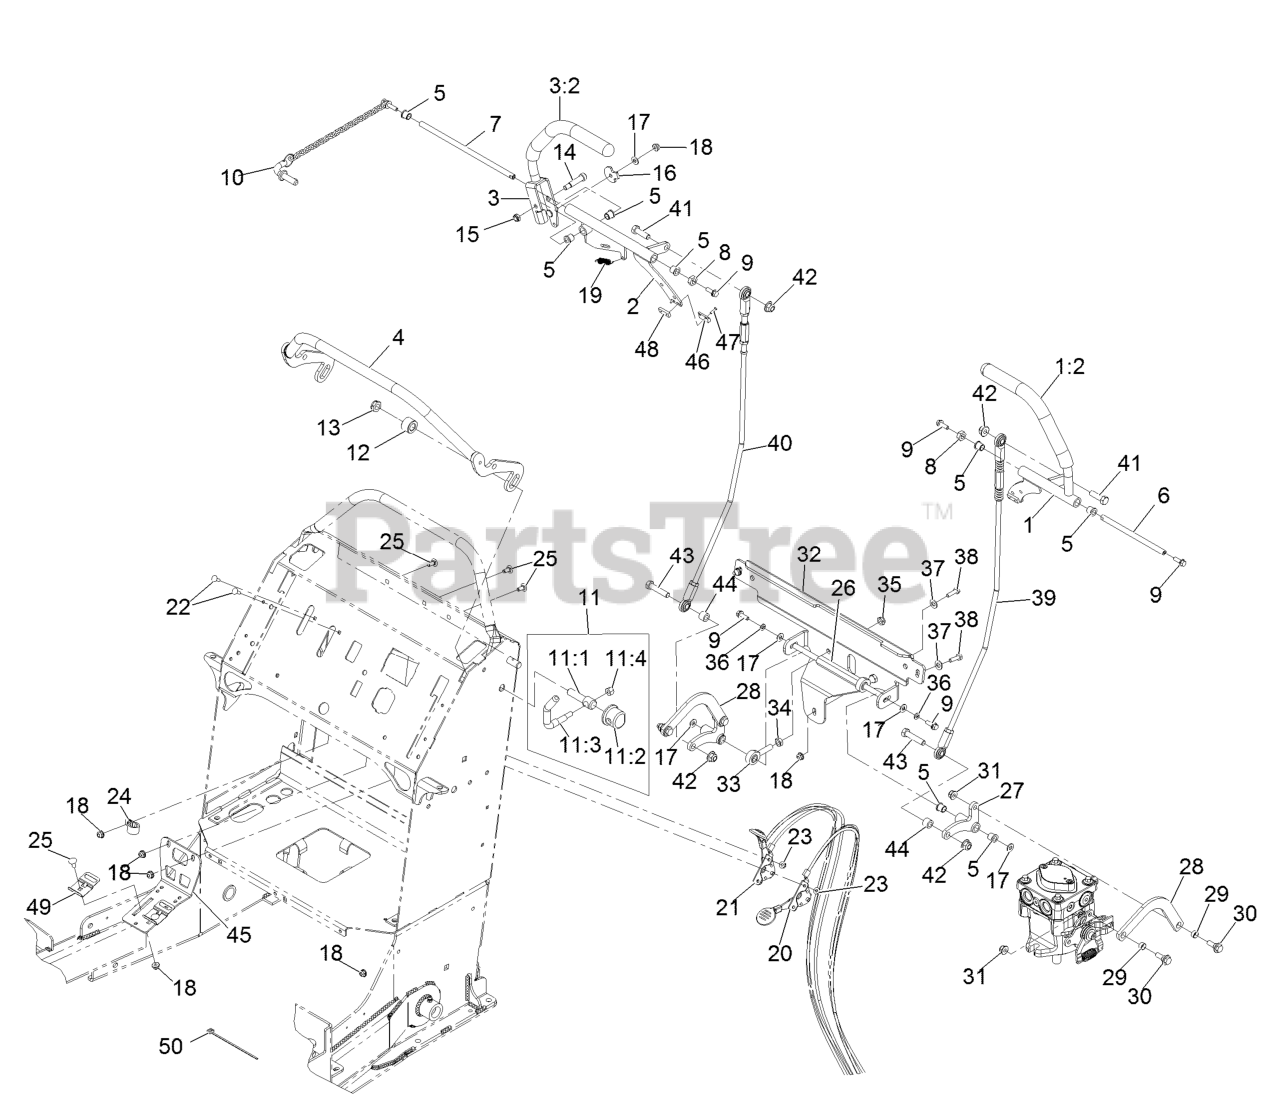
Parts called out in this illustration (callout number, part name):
1	LEVER ASM, LH
1:2	GRIP-HANDLE, CONTROL
2	MOTION CONTROL ASM-RH
3	LEVER ASM, RH
3:2	GRIP-HANDLE, CONTROL
4	TUBE ASM, FRONT SPEED CONTROL
5	BEARING
6	SHAFT-PIVOT, MOTION CONTROL
7	SHAFT-PIVOT, MOTION CONTROL
8	SPACER-SHAFT, DRIVE LEVER
9	SCREW-HHF
10	HOC PIN ASM
11	LEVER ASM
11:1	SCREW-LOCK
11:2	CAP-LOCK
11:4	NUT-LOCK, NI
12	SPACER-CLAMP
13	NUT-HEX
14	SCREW-HSH
15	NUT-LOCK, NI
16	CAM-LEVER
17	WASHER-FLAT
19	SPRING-EXTENSION
20	CONTROL-THROTTLE
21	CONTROL-CHOKE
22	BOLT-CARR
23	NUT-LOCK, FLANGE
24	CLAMP-CABLE
25	SCREW-CARR
26	SHAFT-BELLCRANK PIVOT
27	BELLCRANK-CONTROL, MOTION
28	LINK-BELLCRANK, PUMP
29	BUSHING-SLEEVE
30	SCREW-SHOULDER
31	NUT-HF, NI
32	BRACKET-BELLCRANK
33	BALLJOINT
34	NUT-HJ
35	NUT-HEX
36	SCREW-HH
37	WASHER-PLAIN
38	SCREW-HH
39	LINKAGE-TRACKING CONTROL,LH
40	LINKAGE-TRACKING CONTROL,RH
41	SCREW-HH
42	NUT-HF, NI
43	SCREW-HH
44	SPACER-WHEEL
45	BRACKET, REED SWITCH
46	ACTUATOR-SWITCH, REED
47	SCREW-HH
48	PLATE-TAPPED
49	CLAMP, REED SWITCH
50	TIE-CABLE
